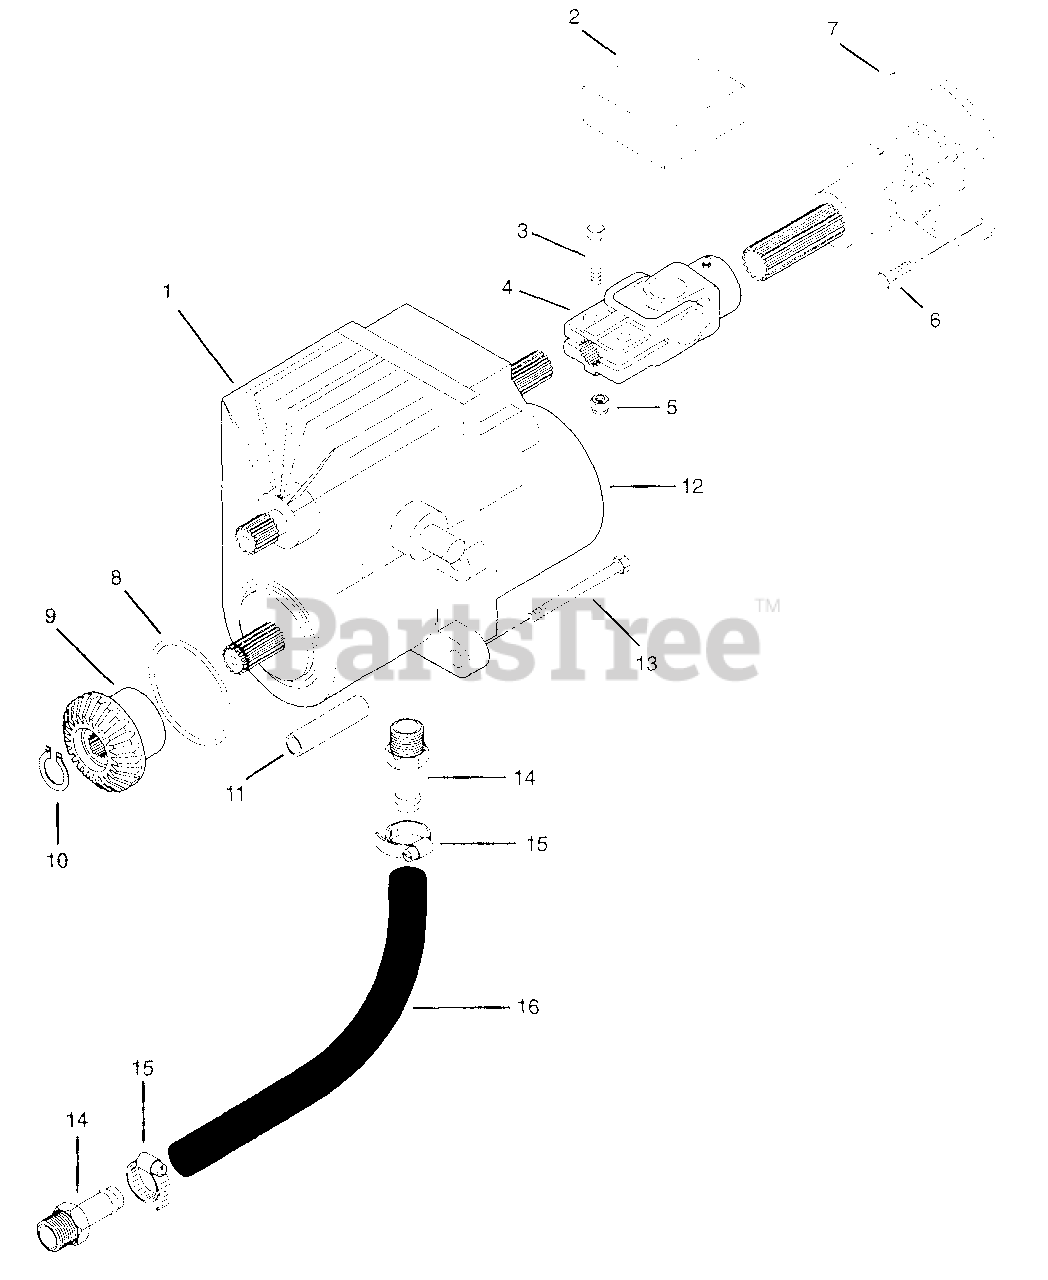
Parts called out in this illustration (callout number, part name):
1	Transmission, Hydraulic
2	Kit, U-Joint Repair
3	Bolt-Hex .38-16 x 1.75 Grade 5
4	Assembly, U-Joint
5	Nut-Locking-Center .38-16
6	Screw, Hex Head 10MM - 1.25 x 20
7	Adapter, Flywheel
8	O-Ring 3.0 x 3.187 x .093
9	Gear
10	Ring-Retaining-External .579 x .93
11	Spacer .385 x .625 x 2.69
12	Oil Filter
13	Bolt-Hex .38-16 x 4.00 Grade 5
14	Fitting-Adapter 88-14
15	Clamp, .88 Diameter Hose
16	Hose .62 Inside Diameter x .91 OD
